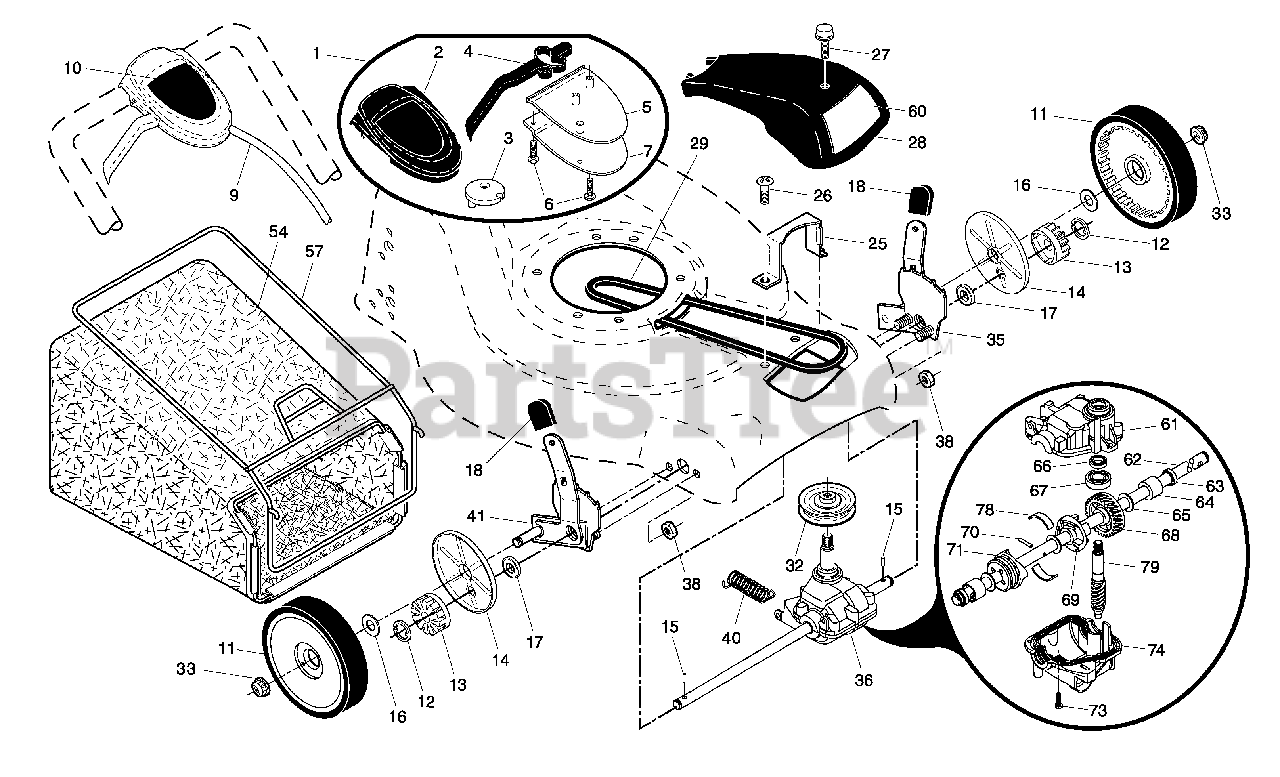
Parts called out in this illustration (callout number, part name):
1	Drive Control Assembly
2	Cover, Drive Control, Upper
3	Pulley
4	Lever, Drive Control
5	Cover, Drive Control, Lower
7	Mounting Bracket, Drive Control
9	Cable, Drive
10	Decal, Drive Control
11	Wheel & Tire Assembly
14	Dust Cover
15	Pawl, Drive
16	Washer 1/2 x 1-1/2 x .134
17	Bearing, Wheel Adjuster
18	Selector Knob
25	Belt Keeper
27	Screw, Pan Head, Self-Tapping #10-24 x 2-3/4
28	Drive Cover
32	Drive Pulley
33	Locknut, Hex
35	Kit, Wheel Adjuster, LH
36	Gearcase Assembly, Complete
38	Locknut, Hex 1/4-20
41	Kit, Wheel Adjuster, RH
54	Grassbag Assembly
57	Frame, Grassbag
60	Decal, Drive Cover
61	Case, Upper
62	Shaft, Output
63	Seal, Output Shaft
66	Seal, Worm Shaft
67	Bearing, Ball
68	Gear, 28 Teeth
69	Fixed Dog Clutch
70	Pin
71	Movable Dog Clutch
73	Screw, Case
74	Case, Lower
78	Spring, Leaf
79	Shaft, Worm
